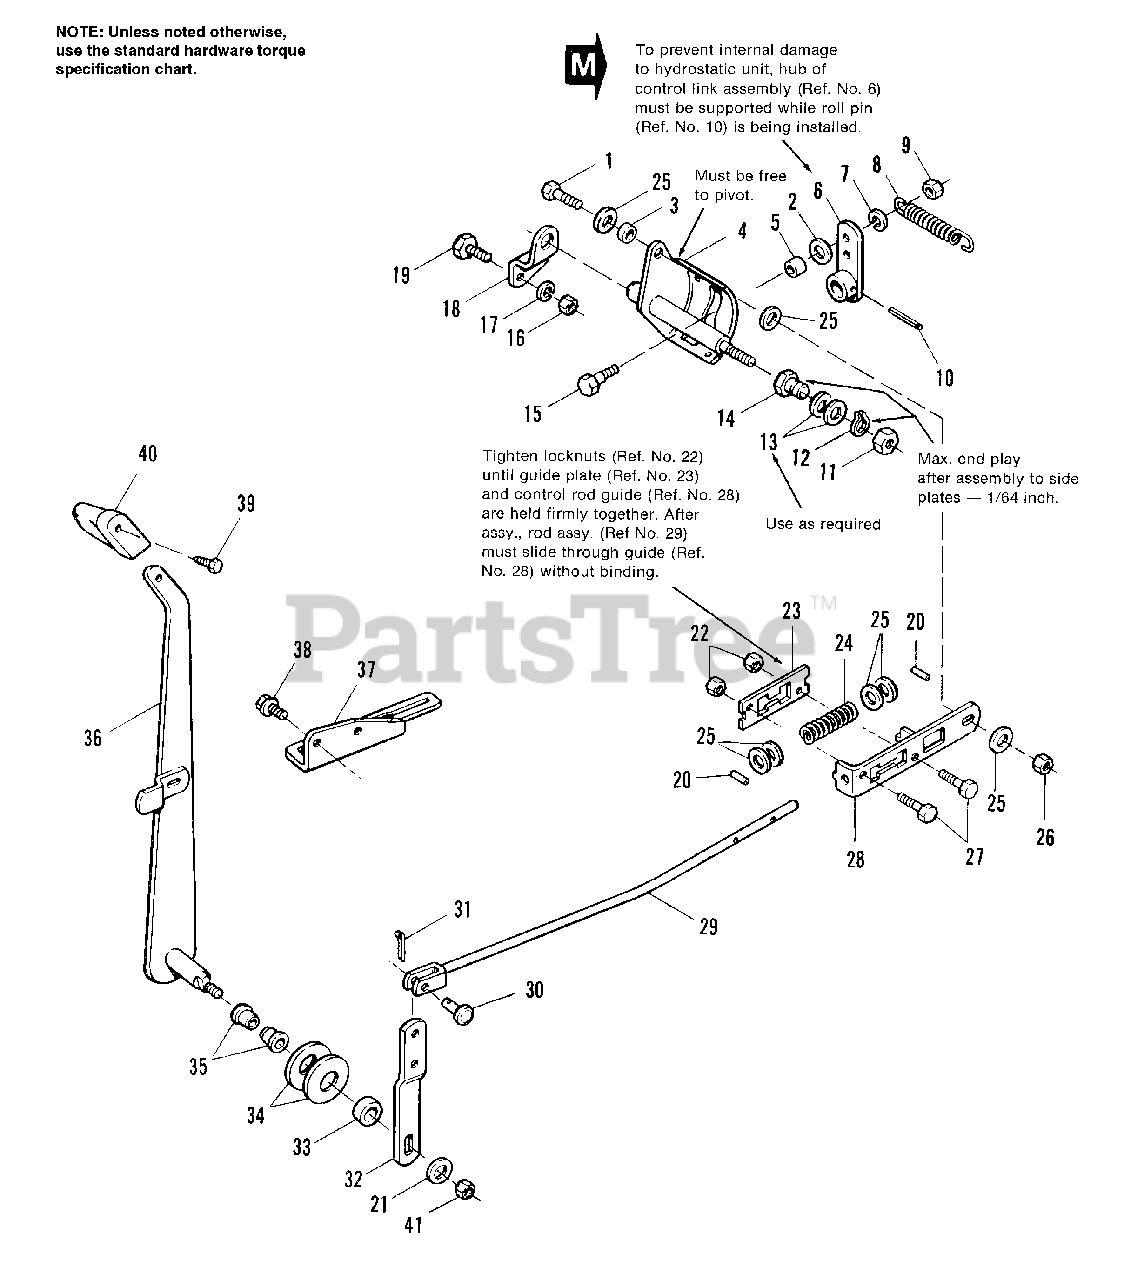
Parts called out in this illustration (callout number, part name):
1	CAPSCREW, Hex Hd, 3/8-16 x 1-1/4
2	WASHER, Plain, 1/4
4	SHAFT ASSEMBLY
5	ROLLER, Cam
6	LINK ASSEMBLY, Control
7	LOCKWASHER, 1/4
9	NUT, Hex, Full, 1/4-20
10	PIN, Roll, 1/4 x 1-1/4
11	LOCKNUT, Hex, Jam, 1/2-13
12	RING, Retaining
13	SHIM
14	NUT, Adjusting
15	BOLT, Shoulder
16	NUT, Hex, Full, 5/16-18
17	LOCKWASHER, 5/16
18	BRACKET, Pivot
19	CAPSCREW, Hex Hd
20	PIN, Roll, 1/8 x 5/8
21	WASHER, 13/32
22	LOCKNUT, Hex, 1/4-20
23	PLATE, Guide
25	WASHER, 3/8
26	NUT, Hex Flange, Whiz Lock, 3/8-16
27	CAPSCREW, Hex Hd, 1/4-20 x 1-1/4
28	GUIDE, Control Rod
29	ROD ASSEMBLY, Control
31	PIN, Cotter, 3/32 x 3/4
34	WASHER, Spring
36	LEVER ASSEMBLY, Control
37	QUADRANT
38	CAPSCREW, Hex Flange Hd, Whiz Lock, 5/16-18 x 1/2
39	CAPSCREW, Hex Washer Hd, Plastite, 1/4-20 x 1
41	LOCKNUT, Nylon, 3/8-16
